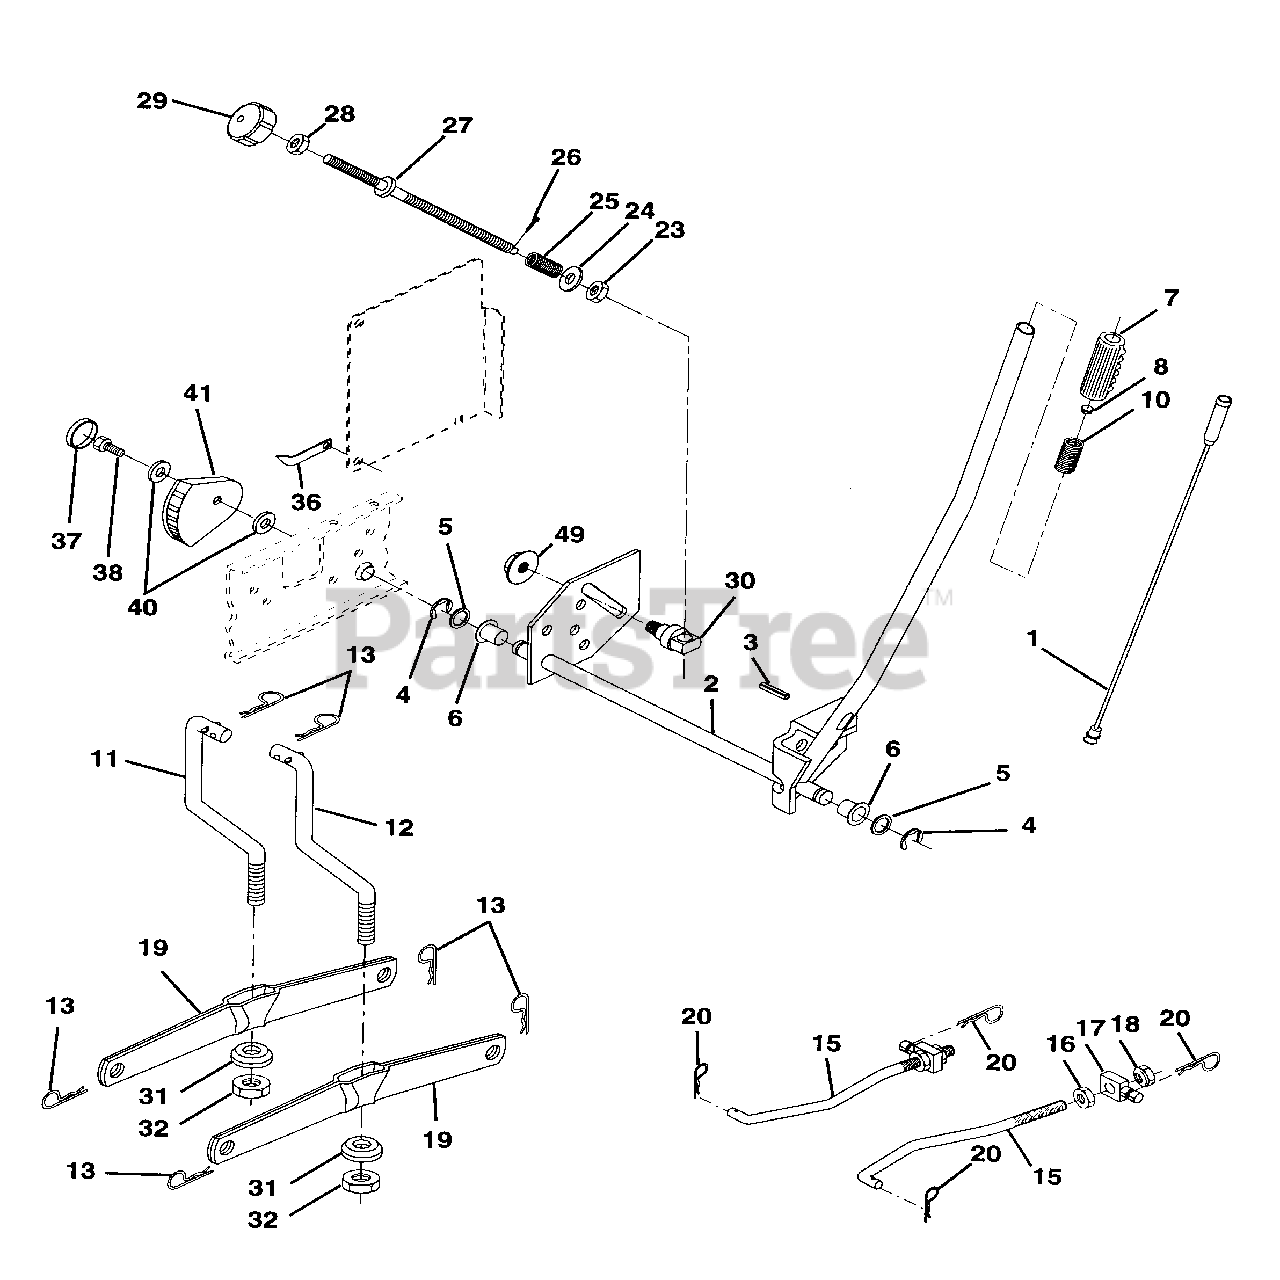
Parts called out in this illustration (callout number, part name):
1	Wire Asm Inner W/plunger 17.32
2	Shaft Asm Lift RH w/Inf
3	Pin Groove 1 500 Zinc
4	E Ring #5133-62
5	Washer 21/32 X 1 X 21 Ga
6	Bearing Nylon Blk 629 Id
7	Grip Handle Fluted Blk
8	Button Plunger Black
10	Spring Cprsn 3 750 Oiled
11	Link Lift LH Fixed Length
12	Link Lift RH Fixed Length
13	Retainer Spring
15	Link Front
16	Nut Jam Hex 1/2-13 Unc
17	Trunnion Blk Zinc
18	Nut Lock W/wsh 1/2-13unc
19	Arm Suspension Rear
20	Retainer Spring
23	Nut Special
24	Washer 13/32 X 5/8 X 16 Ga
25	Spring 2-1/8"
26	Pin Cotter 3/32 X 1/2
27	Rod Adj Lift Zinc 7.49 Wrk Lg
28	Nut Hex Jam 3/8-16 Unc
29	Knob Inf 3/8-16 Unc Blk W/sym
30	Trunnion Infin Height
31	Bearing Pvt Lift Spherical
32	Nut Crownlock 3/8 - 24
36	Pointer Height Indicator
37	Plug Hole Blk 1.485/1.515 Dia.
38	Screw Thdrol 5/16-18 x 3/4
40	Washer 11/32 x 1-1/2 10 Ga.
41	Indicator Height STLT
49	Nut Hex Flange Lock
